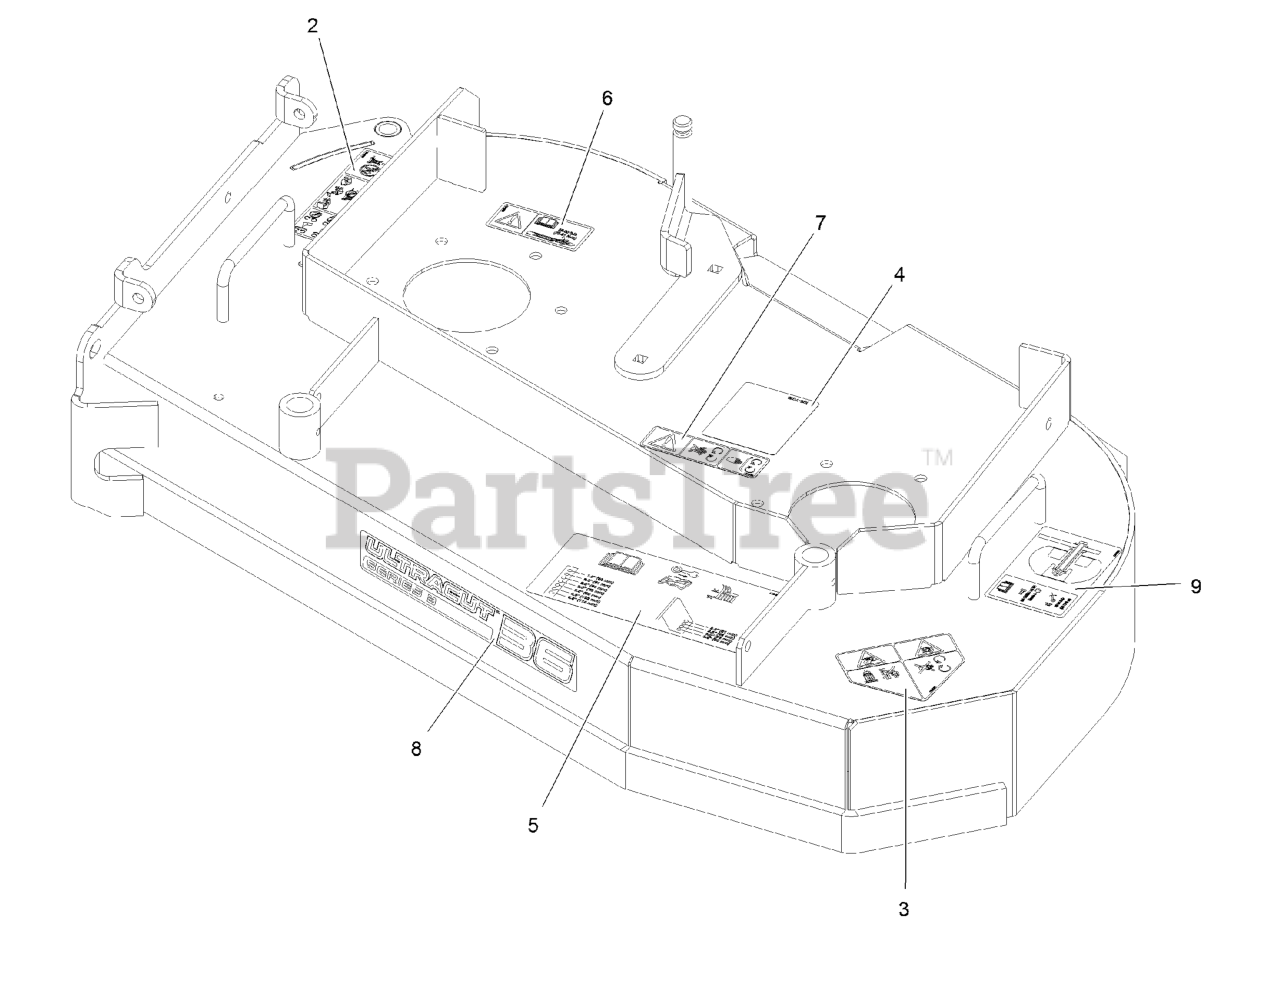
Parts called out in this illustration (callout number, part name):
2	DECAL-WARNING THROWN OBJ
3	DECAL-DANGER
4	DECAL-ROUTING, BELT
5	DECAL-ANTI-SCALP
6	DECAL-TORQUE, BOLT
7	DECAL-COVER, MISSING
8	DECAL-ULTRACUT 36 SERIES 3
9	DECAL-ROLLER MOUNTING
